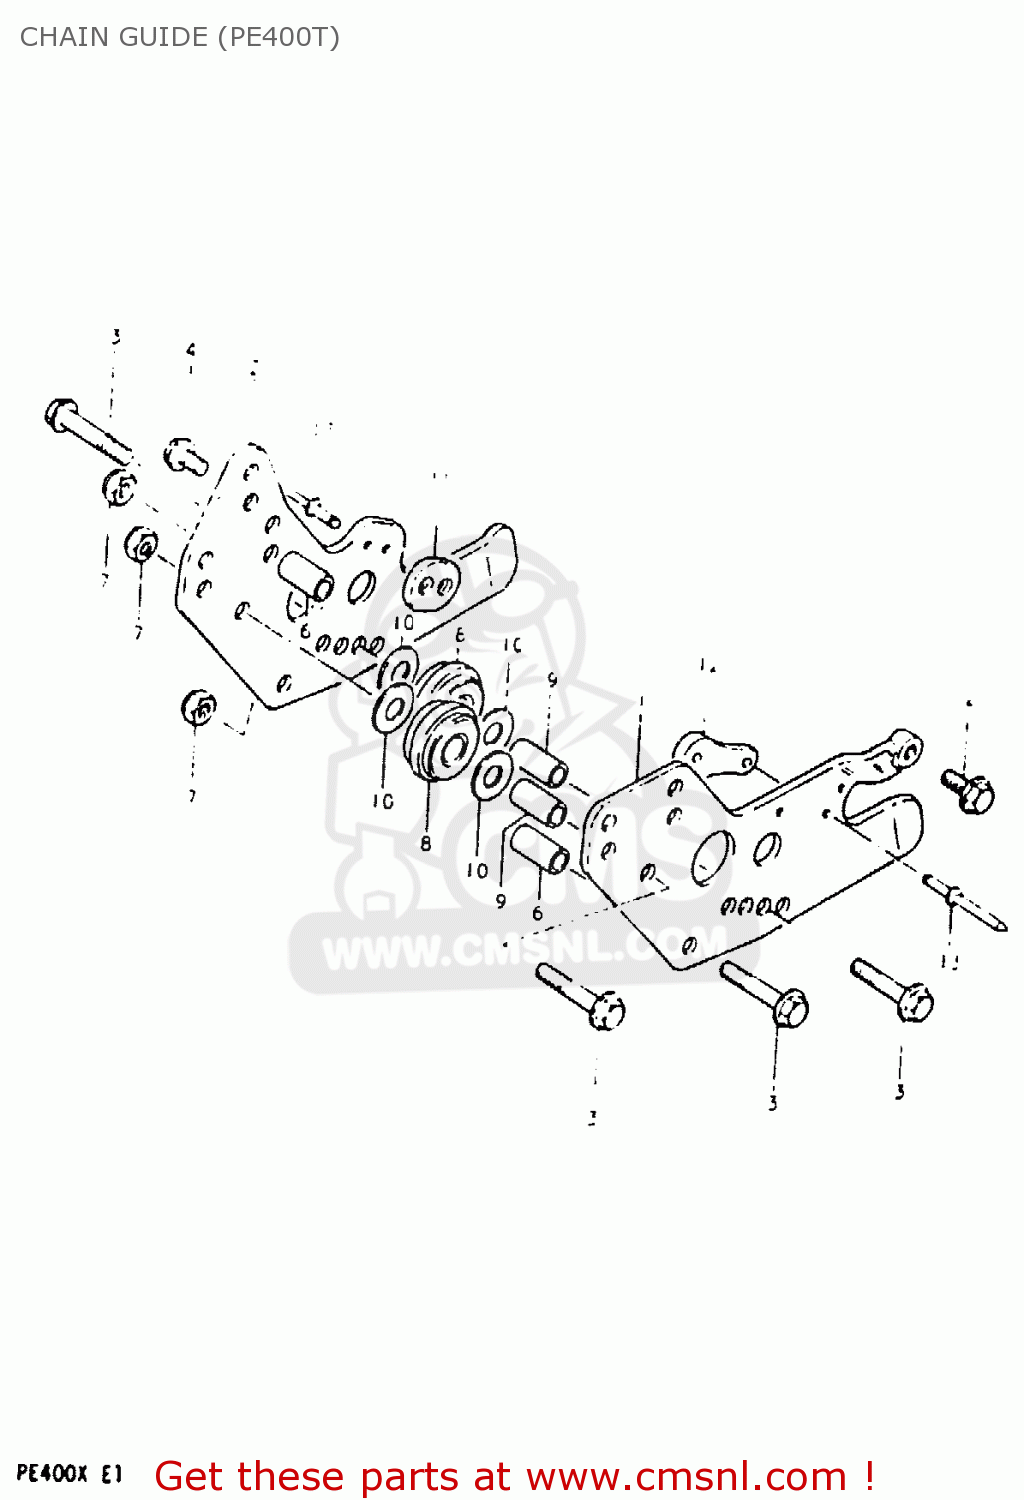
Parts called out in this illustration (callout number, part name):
1	PLATE,CHAIN GUIDE,OUTER
2	PLATE,GUIDE CHAIN
3	BOLT
4	BOLT
5	BOLT
6	SPACER(6.8X10X24.2)
7	NUT
8	ROLLER,CHAIN GUIDE
9	SPACER,CHAIN GUIDE ROLLER
10	WASHER
11	PAD,DRIVE CHAIN GUIDE
12	PAD,DRIVE CHAIN GUIDE
13	RIVET
